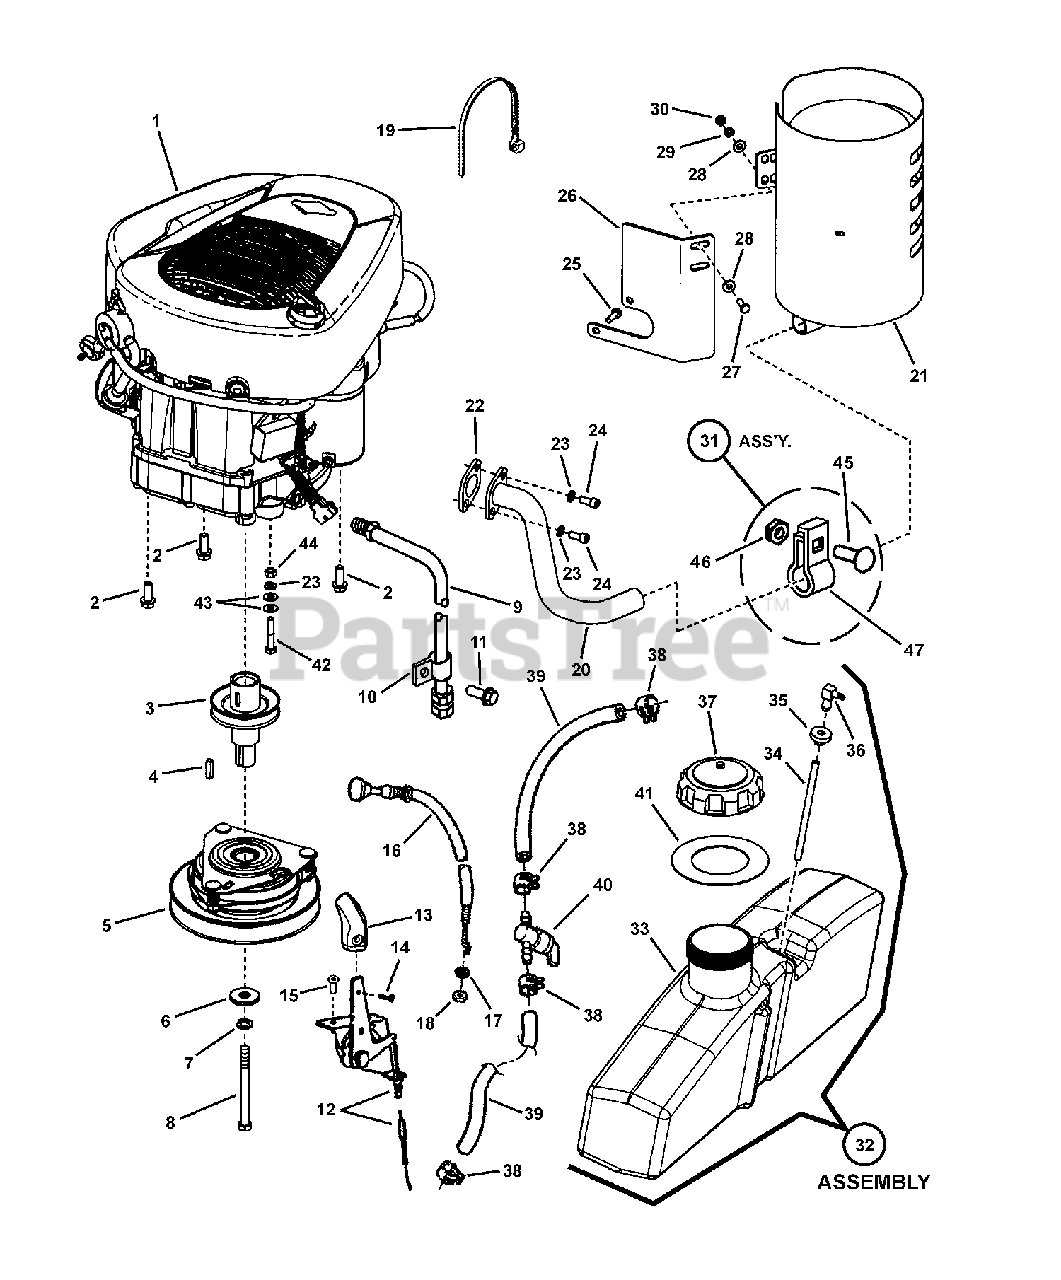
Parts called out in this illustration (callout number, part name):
1	* ENGINE, 18.5 HP Briggs, Intek
2	SCREW, 3/8-16 x 1" Hex Washer Self-Tap
3	ASSEMBLY, Engine Pulley
4	KEY, 1/4 Square x 1"
5	CLUTCH, Ogura JD-11
6	WASHER, .468 ID x 1.50 OD x .188 Flat
7	WASHER, 7/16" Split Lock
8	SCREW, 7/16-20 x 4-1/2" Hex Head Cap, GR 5
9	HOSE, Oil Drain
10	HARNESS CLIP, 5/8"
11	SCREW, 5/16-18 x 5/8" Hex Washer Self-Tap, GR 2
12	CABLE, 26.25" Throttle Control
13	KNOB, Throttle, Red RZT
14	SCREW, #10-16 x 3/4" Pan Head Self-Tap
15	SCREW, 1/4-20 x 5/8" Pan Head Self-Tap (Torx)
16	CABLE, 30" Choke Control
17	WASHER, 3/8" Internal Tooth Lock
18	NUT, 3/8-24 Hex, GR B
19	CABLE TIE, 7"
20	MANIFOLD, 18 HP B&S Intek
21	MUFFLER, RZT
22	GASKET, Exhaust
23	WASHER, 5/16" Split Lock
24	SET SCREW, 5/16-18 x 3/4" Socket Head, GR 8
25	SCREW, 1/4-20 x 3/4" Hex Washer Self-Tap
26	BRACKET, Muffler 18HP Briggs
27	SCREW, 1/4-20 x 3/4" Hex Head Cap, GR 5
28	WASHER, .28 x .63 x .06 Flat, GR 5
29	WASHER, 1/4" Split Lock
30	NUT, 1/4-20 Hex, GR 5 or B
31	ASSEMBLY, Clamp
32	ASSEMBLY, Fuel Tank, RZT
33	FUEL TANK, 3 Gal.
34	DIP TUBE
35	GROMMET
36	ELBOW, 90 Degree
37	CAP, Fuel, 3-1/2"
38	CLAMP, Fuel Line
39	HOSE, Fuel, 5"
40	VALVE, Fuel Shut-Off
41	SEAL, Tank
42	SCREW, 5/16-18 x 1-3/4" Hex Head Cap, GR 5, YZ
43	WASHER, .34 x .69 x .08 Flat
44	NUT, 5/16-18 Hex, GR 5 or B
45	BOLT, 5/16-18 x 1-1/4" Square Neck Carriage
46	NUT, 5/16-18 Hex Flange Lock, GR 5
47	CLAMP, Muffler
